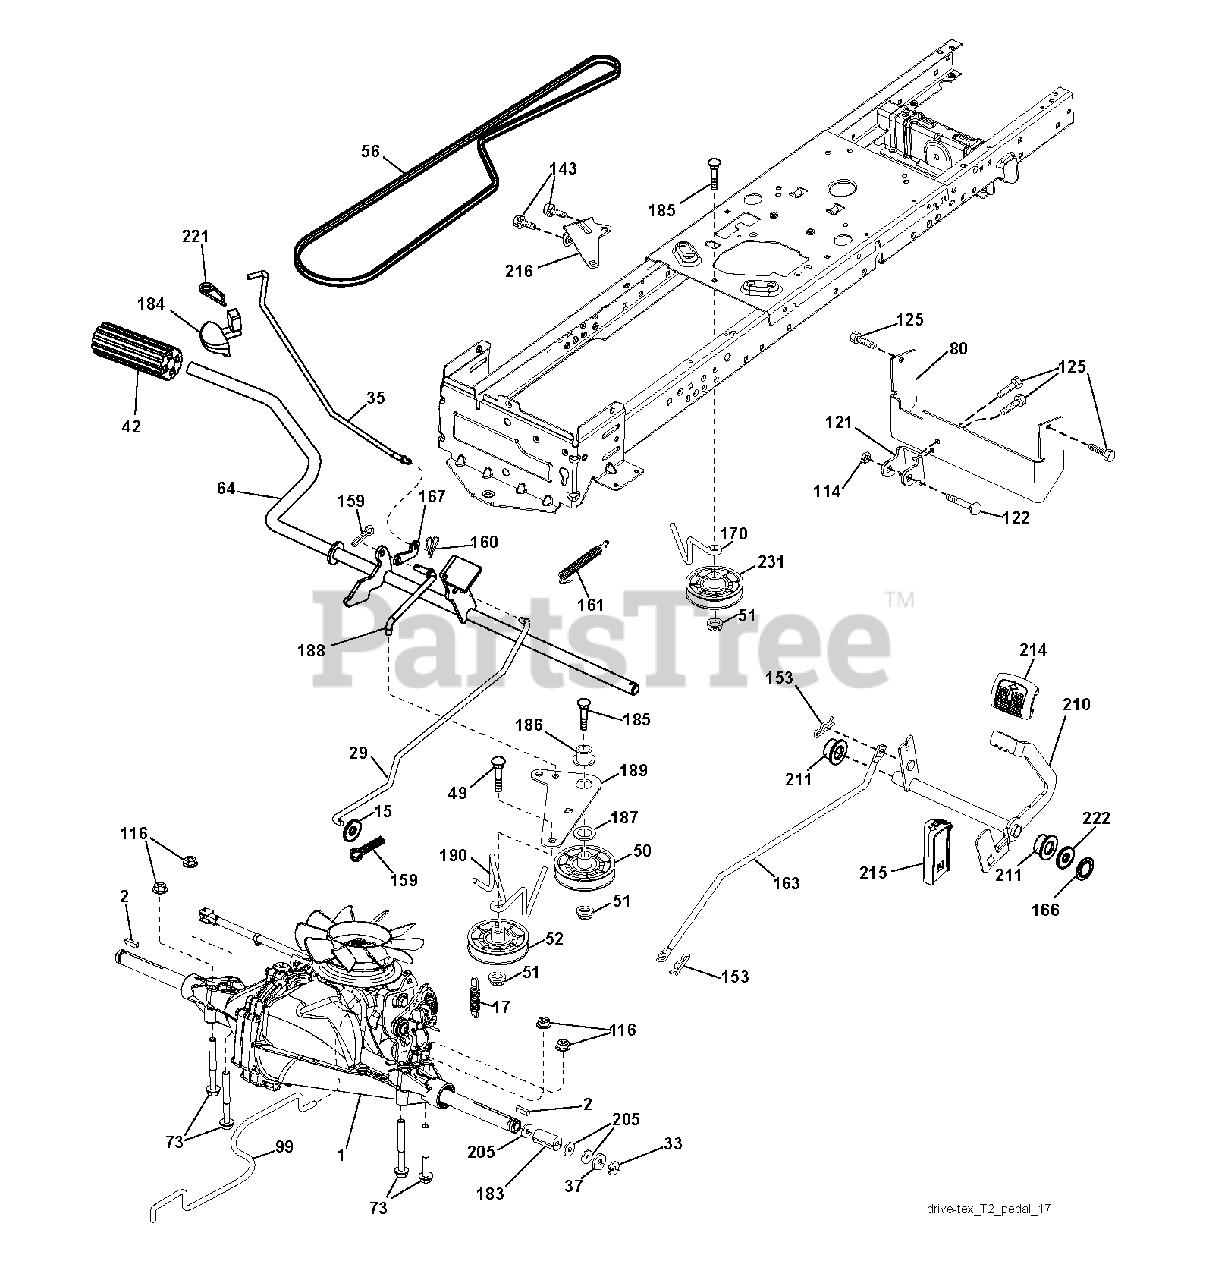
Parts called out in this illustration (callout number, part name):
2	SQUARE KEY
15	WASHER
33	E-RING LT
42	PEDAL COVER T
50	IDLER.FLAT.910.OFFSET
52	IDLER.V-GROOVE.910.OFFSET
64	SHAFT.ASM.PEDAL.BRK.CN
73	BOLT HEX 5/16-18 GR 5
116	NUT LOCK HEX FLANGE 5/16-18
125	SCREW
143	SCREW LT
159	COTTER PIN
160	RETAINER CLIP
161	SPRING, RETURN LT
166	NUT.PUSH.625
167	LATCH BRAKE PARKING
170	KEEPER.CENTER SPAN.1.688
186	SPACER.RETAINER
188	LINK.CLUTCH.GROUND DRI
189	BELLCRANK.GRDDRIVE.NST
190	KEEPER.BELLCRANK.DRIVE
210	ROCKER.ASM.PEDAL.CONTR
211	BEARING RER
214	PAD PEDAL FORWARD
215	PEDAL.REVERSE.TEX.GT.4
216	BRKT.PULLEY.IDLER.WTEX
221	RETAINER.SPRING.CLIP.H
222	WASHER 21/32 X 1-1/4 X 10 GA.
231	PULLEY VGROOVE
